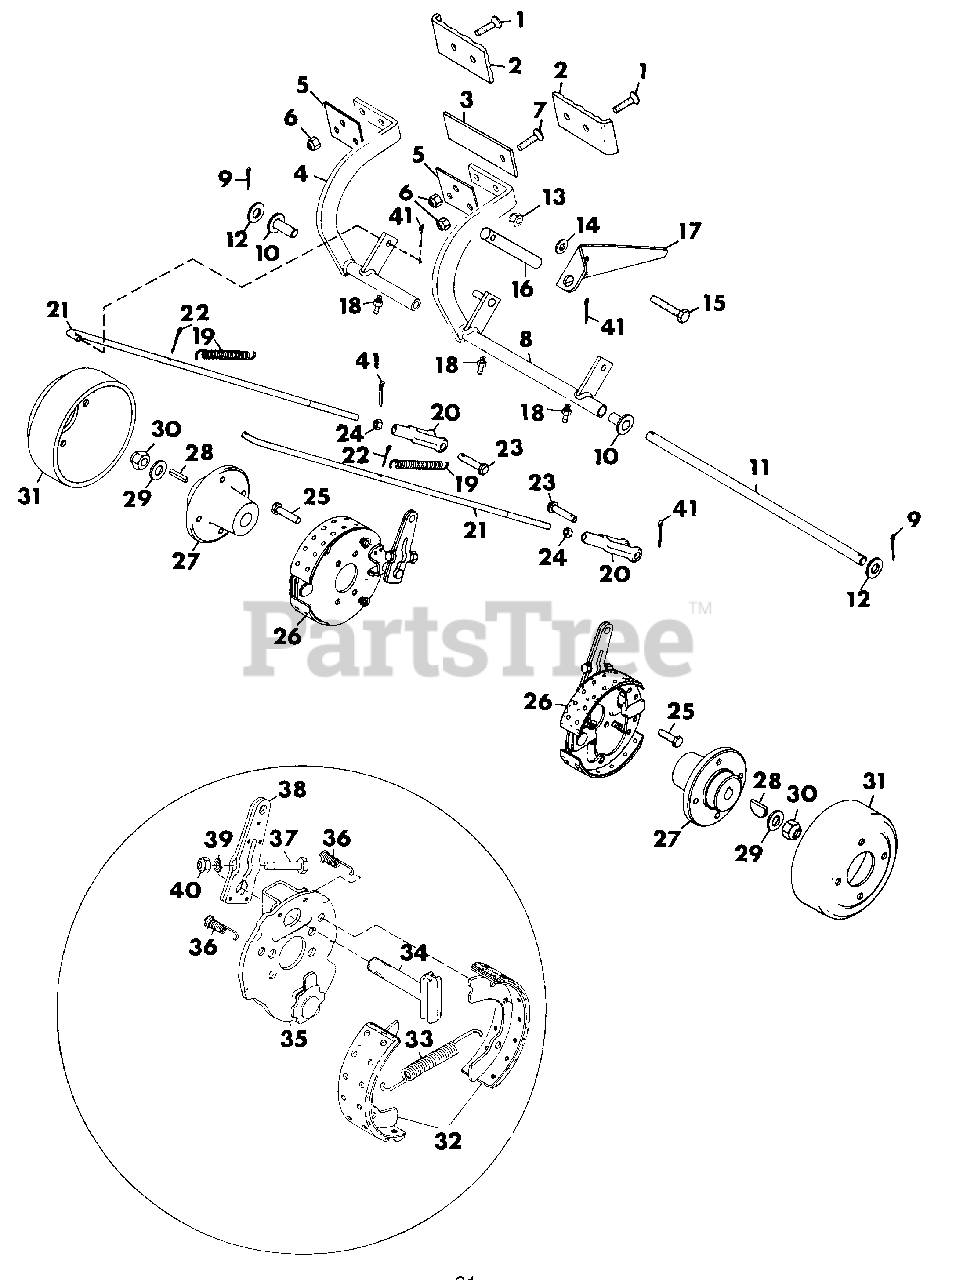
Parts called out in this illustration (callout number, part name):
1	SCREW, MACHINE 1/4-20X1.25
2	PEDAL, BRAKE
3	ARM, BRAKE LOCK
4	WELDMENT, BRAKE PEDAL
5	PLATE, BRAKE LOCK BACKING
6	NUT, LOCK 1/4-20
7	SCREW, MACHINE 1/4-20X1.0
8	WELDMENT, BRAKE PEDAL
9	PIN, COTTER .125X1.25
10	BEARING
11	SHAFT, BRAKE
12	WASHER, FLAT .656X1.250X.100
13	NUT, LOCK 3/8-16
14	WASHER, NYLON .375X.75X.060
15	BOLT, HEX 3/8-16X2.25
16	ROD
17	LEVER, BRAKE LOCK
18	FITTING, LUBE 1/4-28
19	SPRING, EXTENSION 5.5X.5X20 RATE
20	CLEVIS, 3/8-24 ADJUSTABLE
21	ROD, BRAKE
22	PIN, COTTER .125X.75
23	PIN, CLEVIS .375X.948
24	NUT, JAM 3/8-24 HEX HD
25	BOLT, HEX 3/8-16X.75
26	BRAKE, 7X1.75 MECHANICAL
27	HUB, OFC 60"
28	KEY, WOODRUFF .250X2.125 SOFT
29	WASHER, FLAT .813X2.0X.148
30	NUT, LOCK 3/4-10
31	DRUM, 7X1.75
32	SHOE, BRAKE
33	SPRING, SHOE RETURN
34	CAM, BRAKE
35	PLATE, BACK
36	SPRING, SHOE RETAINING
37	BOLT, HEX 5/16-24X1.75
38	ARM, CAM LEVER
39	WASHER, LOCK 5/16 REG.
40	NUT, HEX 5/16-24
41	PIN, COTTER .09X.75
